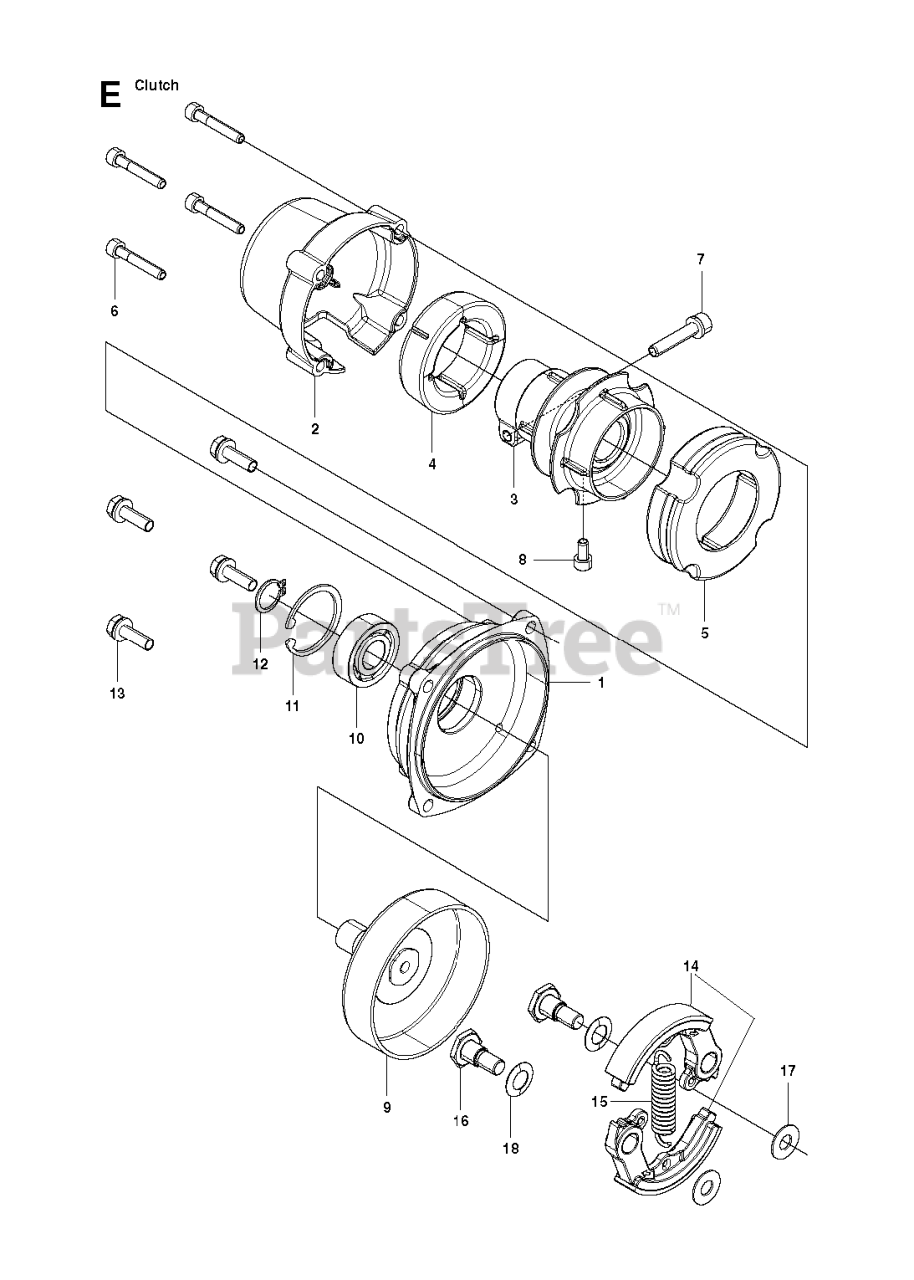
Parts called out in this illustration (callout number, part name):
6	SCREW MC6S 5X30
7	SCREW MC6S 6X30
8	SCREW MC6S 5X10
9	DRUM
10	BALL BEARING 6202-2RS1
